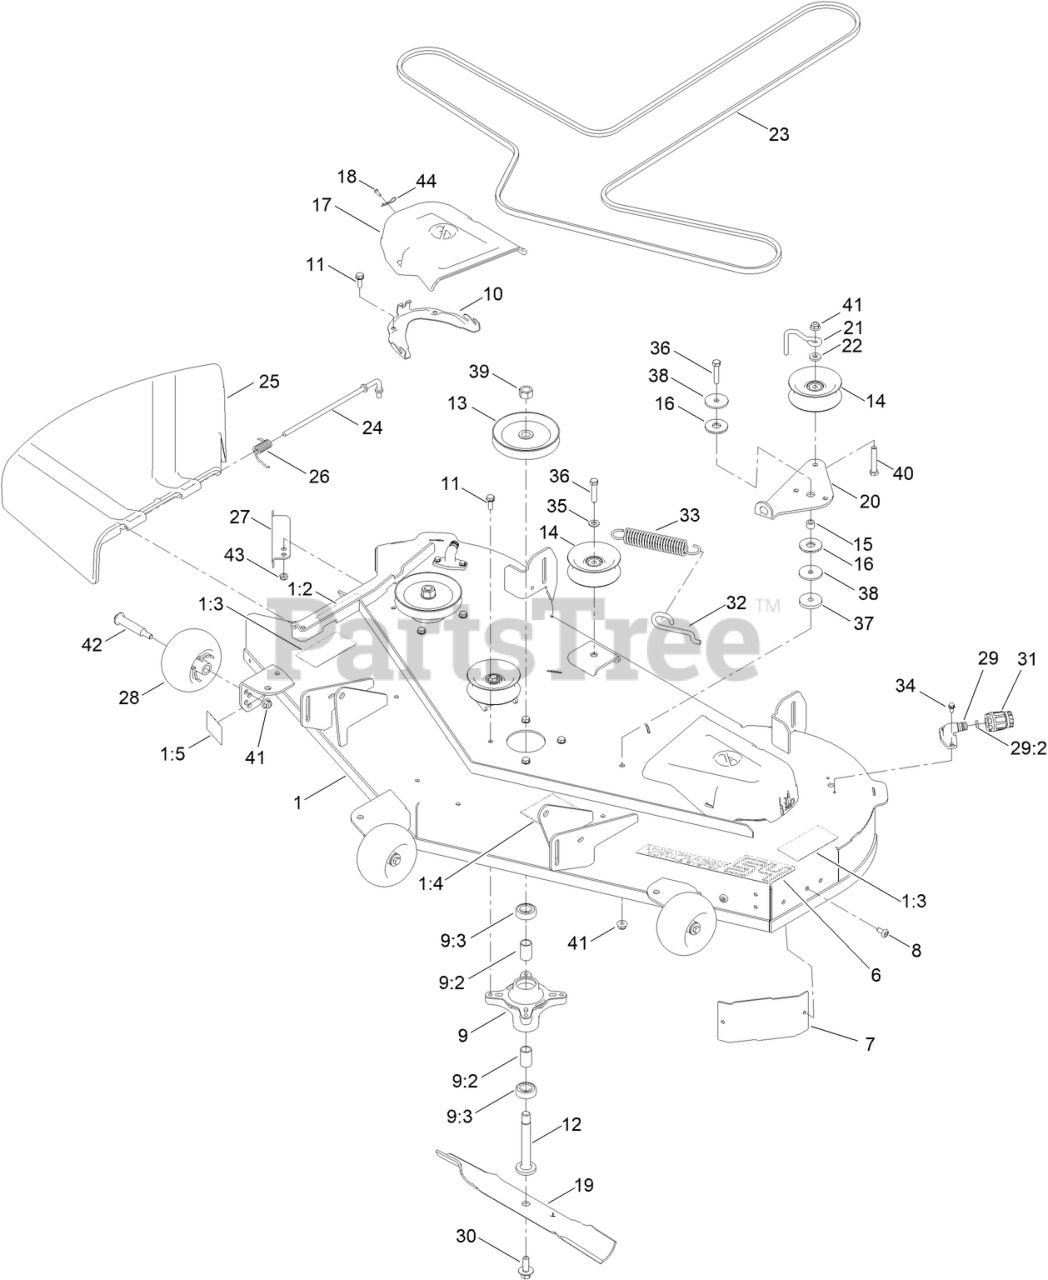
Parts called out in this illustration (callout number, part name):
1	54 IN DECK DECAL ASM
1:2	DECAL-DANGER DEFLECTOR [BLK-TXT]
1:3	DECAL-DANGER, DECK
1:4	DECAL-ROUTING, BELT
1:5	DECAL-SCALP, ANTI
6	DECAL - IRON FORGED 54
7	BAFFLE-CORNER
9	SPINDLE ASM
9:2	SPACER
9:3	BEARING-BALL
10	BRACKET-COVER, BELT
11	SCREW-TAPTITE
12	SHAFT-SPINDLE
13	PULLEY ASM
14	PULLEY-IDLER, FLAT
15	SPACER
16	WASHER-FRICTION, COMPOSITE
17	COVER-BELT
18	SCREW
19	BLADE-HI LIFT
20	ARM-IDLER
21	BELT GUIDE - IDLER
22	SPACER-HUB, BLOWER
23	BELT-V (A SEC, 145.5 EL)
24	ROD-PIVOT
25	DEFLECTOR-DISCHARGE
26	SPRING-TORSION
27	BAFFLE-CUTOFF
28	ROLLER-SCALP, ANTI
29	FITTING-WASHOUT
29:2	O-RING
30	BOLT-BLADE, SEMS
31	CONNECTOR-HOSE
32	HOOK-RETURN SPRING
33	SPRING-EXTENSION
34	SCREW-HWH
35	WASHER-FLAT
36	SCREW-HH
37	WASHER-PLAIN
38	WASHER-REBOUND
39	NUT-HEX
40	SCREW-HH
41	NUT-HF, NI
42	BOLT-SHOULDER
44	PIN-HAIR
